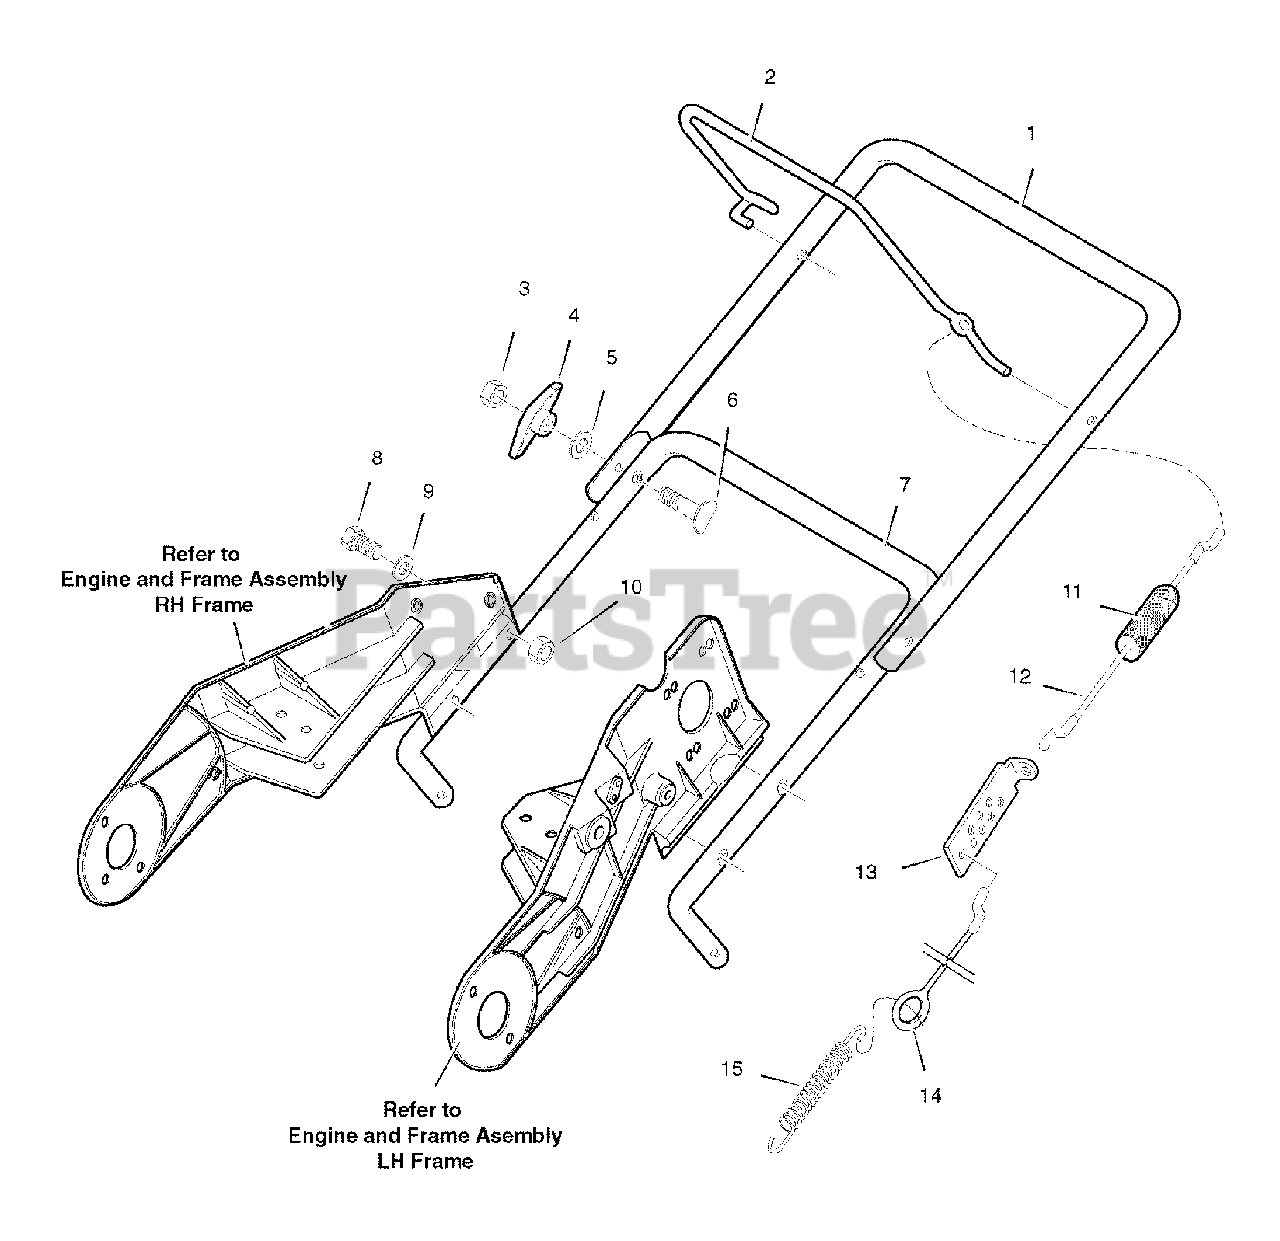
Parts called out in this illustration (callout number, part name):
1	HANDLE, UPPER
2	BAIL, CONTROL
3	NUT, 5/16-18 HEX
4	KNOB, WING
5	WASHER, FORM .344 I.D.
6	BOLT, 5/16-18 X 2.00
7	HANDLE, LOWER
8	SCREW, 1/4-20 X 1.25
9	WASHER, FLAT .281 X .63 X .065
10	NUT, .25-20 HEX CONTROL LOCK
11	BOOT, CLUTCH SPRING
12	CABLE, UPPER CONTROL
13	BRACKET, CABLE ADJUST
14	CABLE, LOWER CONTROL
15	SPRING, EXTENSION .75 O.D. X .069 X 2.00
